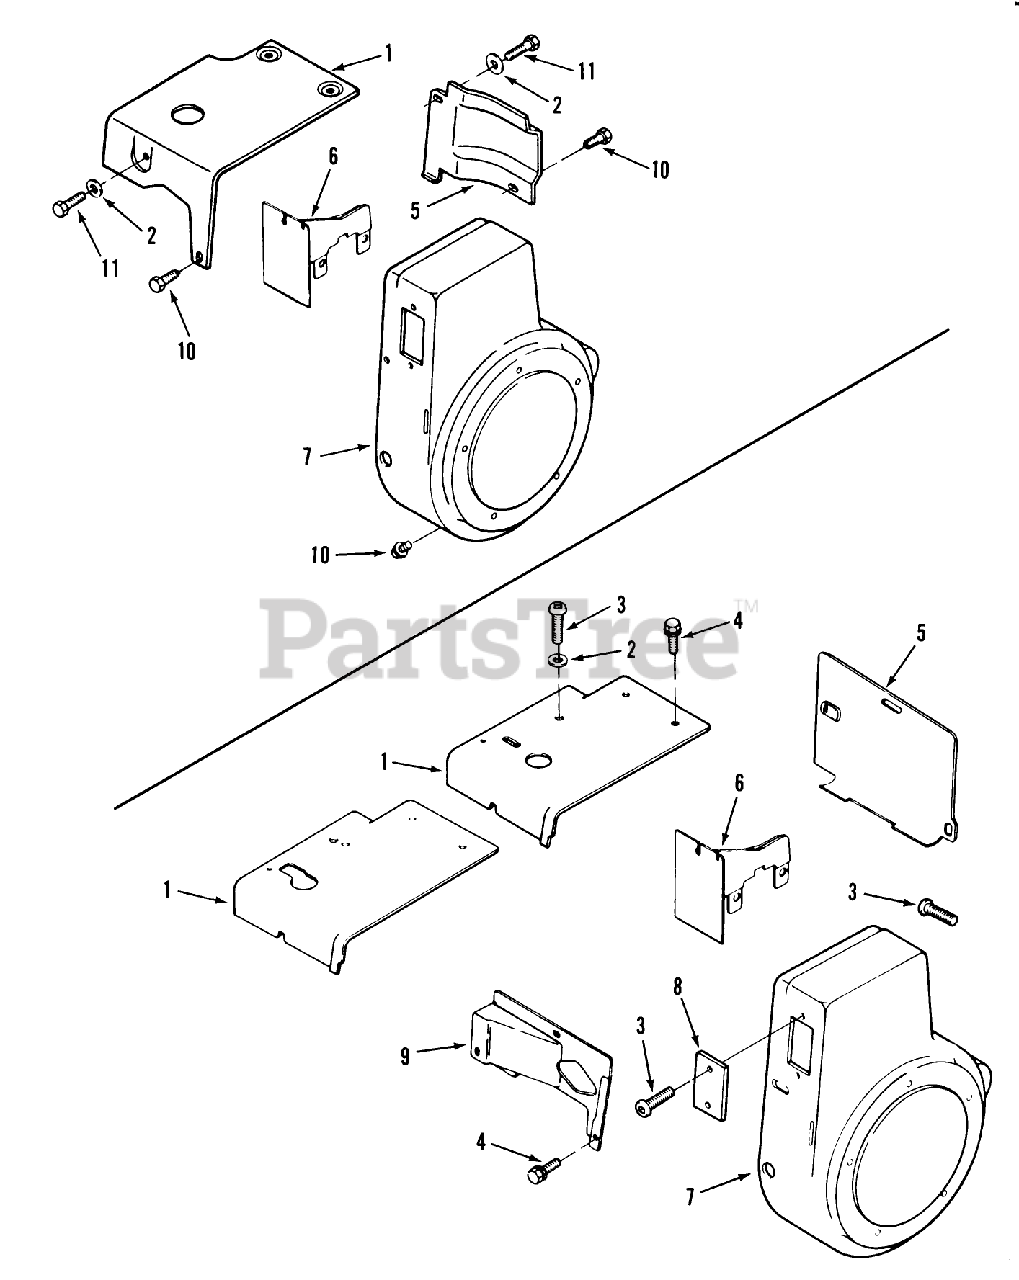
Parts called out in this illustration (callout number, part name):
1	KOHLER 41-063-11
2	KOHLER X-25-53
3	KOHLER 47-086-08
4	KOHLER 52-086-11
5	KOHLER 41-063-09
6	KOHLER 41-063-13
7	KOHLER 41-027-47
8	KOHLER 41-096-23
9	KOHLER 47-063-06
10	KOHLER X-67-83
11	KOHLER X-132-5
